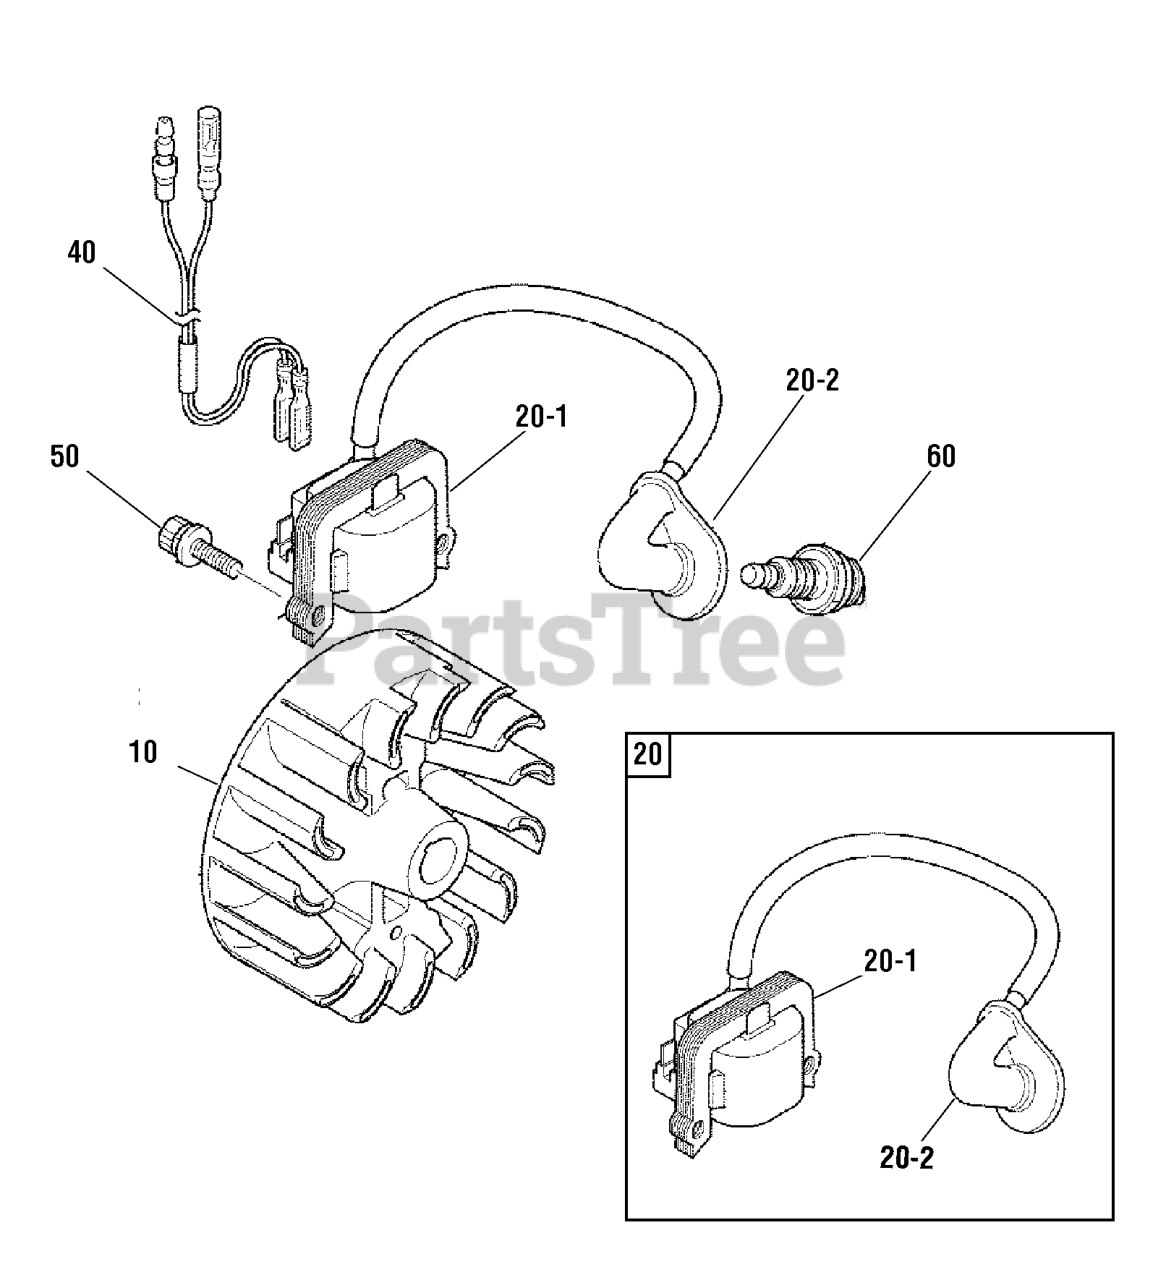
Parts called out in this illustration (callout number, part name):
20	COIL ASSEMBLY
20-1	COIL, Ignition
20-2	CAP, Plug
40	WIRE, Lead
50	BOLT & WASHER
